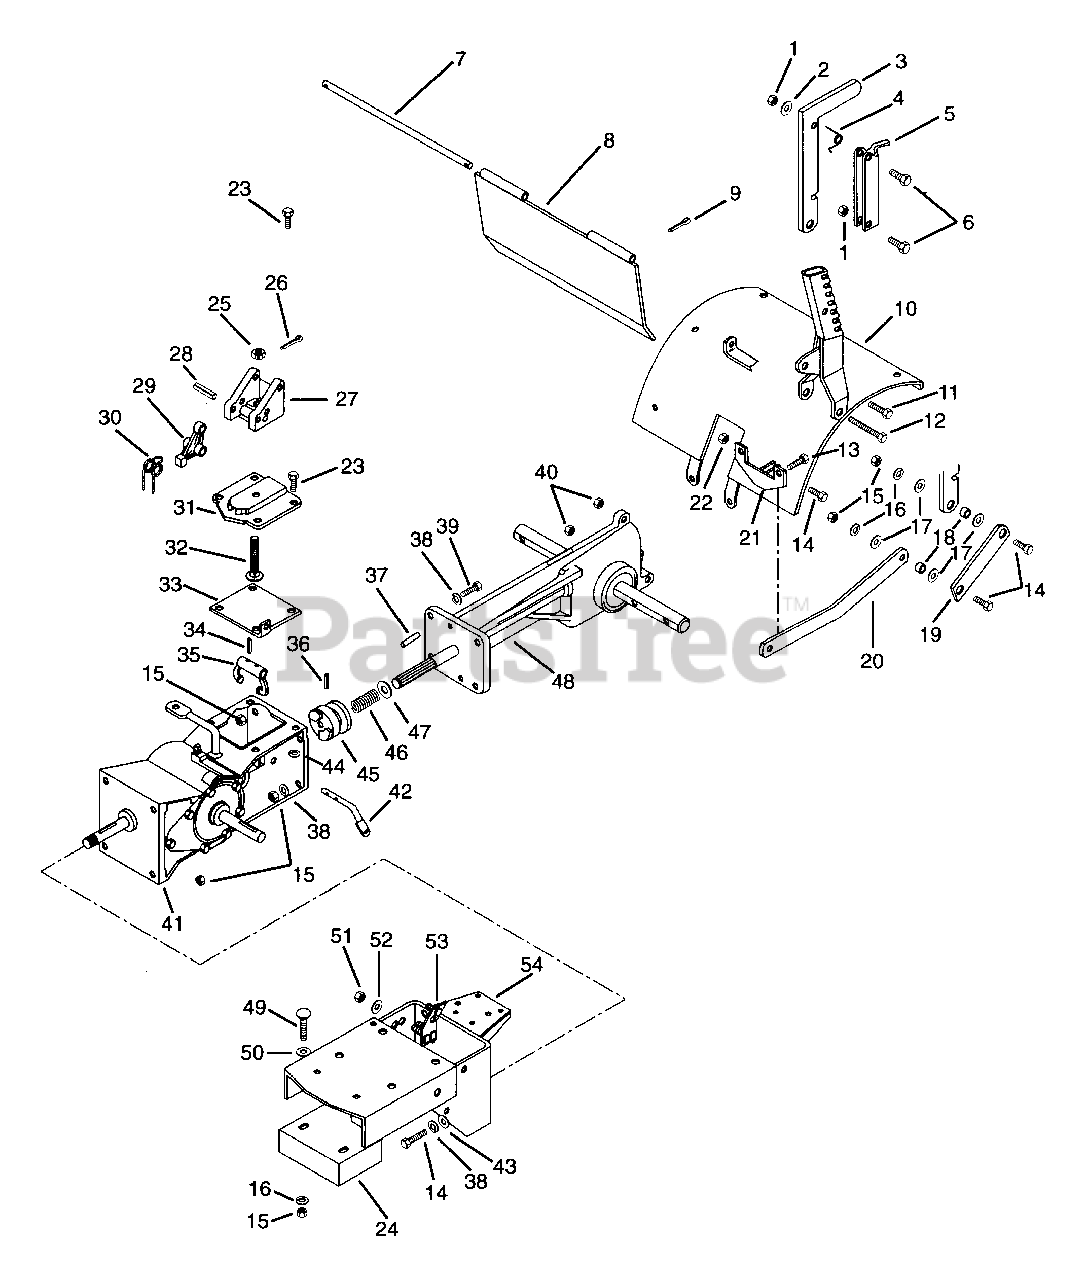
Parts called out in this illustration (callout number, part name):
1	NUT-LK-CTR .250-20 PL
2	WSHR-FL-STL.281X.62X.065 PL
3	HANDLE WELDMENT
4	SG-TORS .050X.25X2.33
5	TRIGGER
6	BLT-HEX .25-20X1.25 PL GR5
7	TAILBOARD PIN
8	TAILBOARD WELDMENT
9	PIN COTR .09X.50 PL
10	TINE HOOD W/DECAL
11	BLT-HEX .31-18X1.25 PL GR2
12	BLT-HEX .31-18X3.50 PL GR2
13	BLT-HEX .38-16X2.25 PL GR2
14	BLT-HEX .38-16X1.25 PL GR 2
15	NUT-HEX .375-16
16	WSHR-LK .375X.094 MED PL
17	WSHR-FL-STL .382X.812X.062
18	SPACER BUSHING .63 X .38 X .27
19	CHISEL POINT
20	DRAG LINK
21	PIVOT BRACKET
22	NUT-LK-CTR .375-16 GR A PL
23	BLT-HEX .31-18X1.25 PL GR2
24	WEIGHT WAFER
25	NUT-SL .50-13
26	PIN-COTR .12X1.0 PL
27	HANDLEBAR BRACKET
28	PIN-ROLL .313X2.00
30	SG-TORS .109X.88X2.25
31	PIVOT CAP
32	SWIVEL BOLT
33	PIVOT BRACKET
34	PIN-ROLL .188X1.00
35	CLUTCH FORK
36	PIN-ROLL .125X1.00
37	PIN-GRV .375X1.00 TP C
38	WSHR-LK .375X.115 HVY PL
39	BLT-HEX .38-16X1.75 PL GR2
40	NUT-LK .312-18 GR A PL
41	TRANSMISSION GEARCASE ASSY
42	TINE ENGAGING FORK SHAFT
43	WSHR-FL-STL.406X.812X.065PL
44	NUT-LK .312-18 GR A PL
45	TILLER JAW CLUTCH
46	SG-COMP .080X.97X2.18 WLD14
47	WSHR-FL-STL .755X1.375X.125
48	TILLER GEAR CASE - C.I.
49	BLT-RDHDSQNK .38-16X1.75 PL
50	WSHR-FL-STL .630X1.005X.062 PL
51	NUT-LK .312-18 GR A PL
52	WSHR-FL-STL .323X.625X.062 PL
53	BELT FINGER BRACKET
